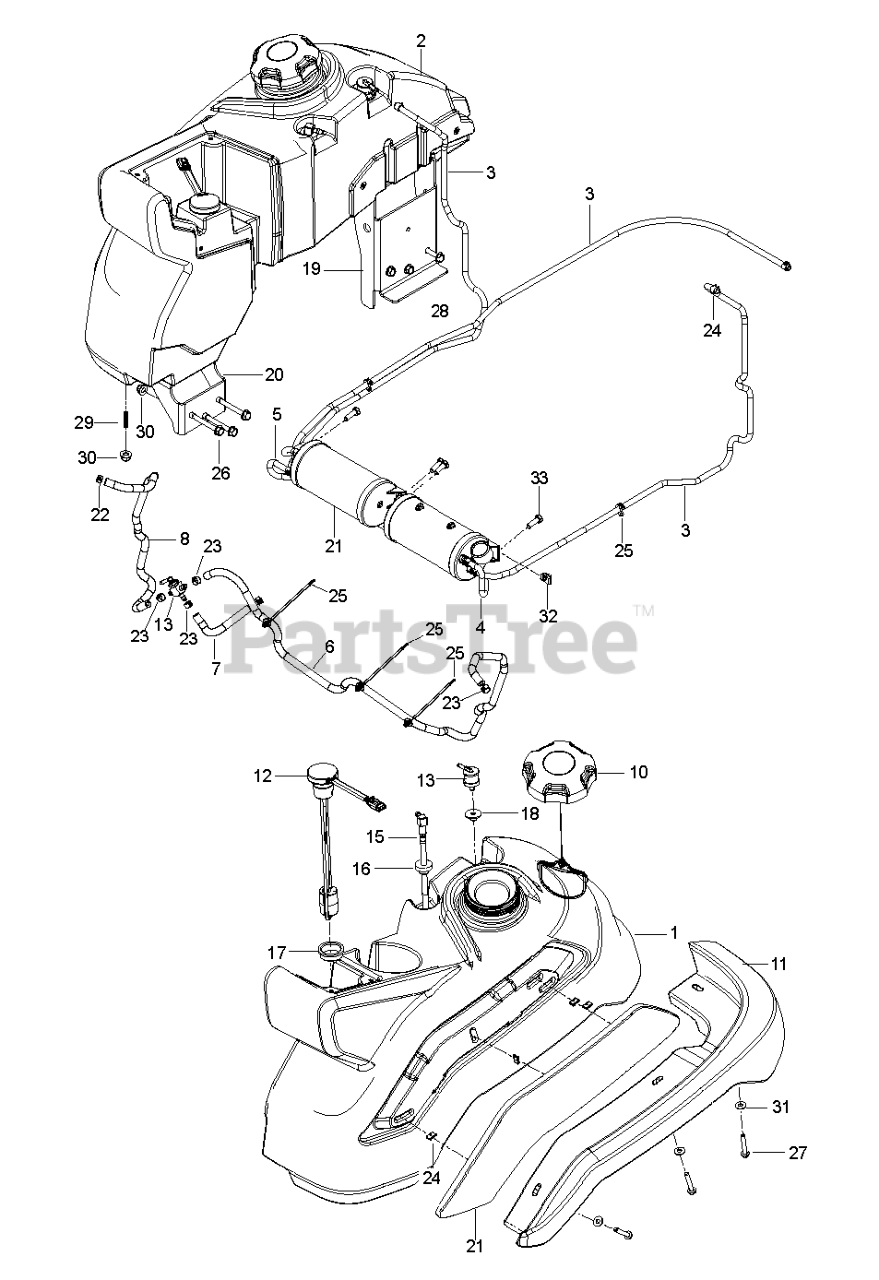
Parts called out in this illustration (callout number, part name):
1	TANK.UNIT.ASM.LH.2018..379IN
2	TANK.ASSY.RH.2019.
3	HOSE.3/16".VAPOR.LINE.38"LGTH
4	CANISTER.FLEX.6.3GAL3/16".TANK
5	HOSE 3/16" VAPOR LINE 13" LENG
6	HOSE 1/4" LOW PERMEATION FUEL
8	HOSE.1/4".LOW.PERM.FUEL.LN.24"
9	TEE, FUEL LINE 3/16"
10	CAP, FUEL
11	GUARD.MUD.LH
12	SENSOR.FUEL.LVL.FLOAT.V500
13	VALVE.FUEL.CHECK
14	FUEL VALVE
15	TUBE.ASM.FUEL.TANK.PICK-UP.LH
16	BUSHING OUTLET T
17	GROMMET, FUEL SENSOR
18	GROMMET.CHECK.FUEL
19	BRACKET.FUEL.TANK.REAR.SUP.431
20	BRACKET.FUEL.TANK.REAR.SUP.431
21	COVER.LH.FUEL.TANK/CONSOLE APP
22	HOSE CLAMP
23	CLAMP, HOSE
24	CLIP.U-TYPE
25	CABLE.TIE.6".FIRTREE.PZ.REFRES
26	BOLT HEX FLGHD 5/16-18X3 GR. 5
27	SCREW.1/4-20X1.5IN.HEX.MACH
28	SCREW
29	SCREW.5/16-18X1.25"THREADED
30	5/16-18 NYLOC FLANGE NUT
31	WASHER
32	1/4-20 U NUT
33	BOLT
